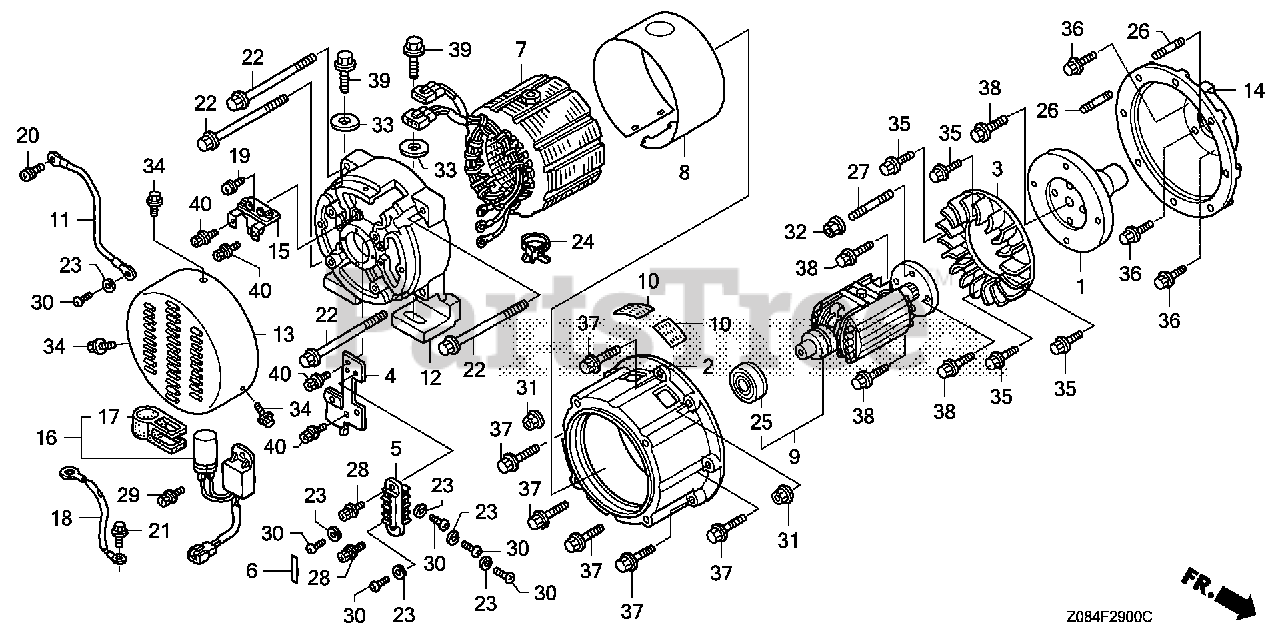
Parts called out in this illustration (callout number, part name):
1	COUPLING, SHAFT
2	HOUSING, FR.
3	FAN, GENERATOR COOLING
4	BRACKET, A.C. OUT TERMINAL
5	TERMINAL, A.C. OUT
7	STATOR ASSY.
8	COVER, STATOR
10	PLATE, HOUSING
11	WIRE, GROUND
12	HOUSING, RR.
13	COVER, GENERATOR END *NH105* (MAT BLACK)
14	BRACKET, FR.
15	BRUSH ASSY.
16	RECTIFIER, REGULATE
17	RUBBER, CUSHION
18	CABLE, SUB-GROUND
19	SCREW-WASHER (4X8)
20	SCREW-WASHER (6X12)
21	BOLT, GROUND (6X16) (WASHER 12.5MM) (ZN)
22	BOLT, FLANGE (10X170)
23	WASHER, SPRING (6MM)
24	STRAP, CABLE (118MM) (BLACK)
25	BEARING ASSY. (6306NCX)
26	BOLT, STUD (8X32)
27	BOLT, STUD (10X40)
28	BOLT-WASHER (5X20)
29	BOLT-WASHER (6X20)
30	SCREW, PAN (6X8)
31	NUT, FLANGE (8MM)
32	NUT, FLANGE (10MM)
33	WASHER, PLAIN (12MM)
34	BOLT, FLANGE (6X8)
35	BOLT, FLANGE (8X20)
36	BOLT, FLANGE (8X25)
37	BOLT, FLANGE (8X35)
38	BOLT, FLANGE (10X35)
39	BOLT, FLANGE (12X35)
40	BOLT-WASHER (6X15)
